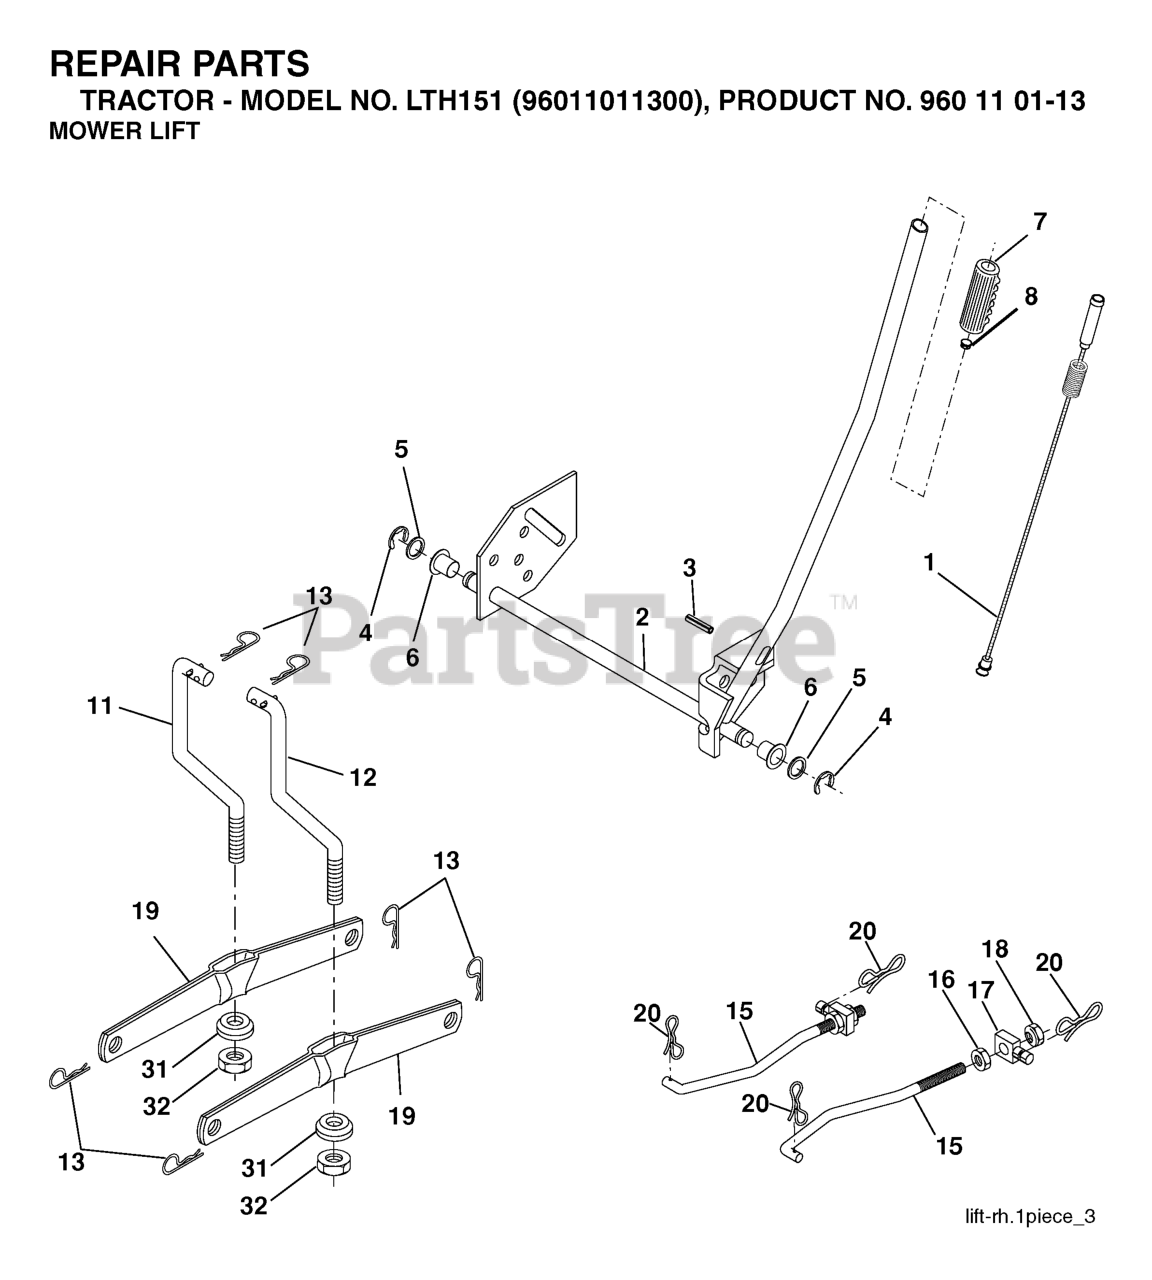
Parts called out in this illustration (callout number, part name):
1	WIRE ASM INNER W/ PLUNGER LT
2	SHAFT ASM R HANDLE
3	PIN GROOVE.
4	RETAINING RING LT
6	BEARING.NYLON
8	PLUNGER BUT KIT
11	LINK LIFT LH
12	LINK LIFT RH
13	RETAINER-SPRNG RB
15	LINK.SUSPENSION.FRONT
16	NUT.HEX.JAM.1/2-13
18	NUT.LK.W/WSH.1/2.
19	ARM.REAR.SUSPENSION
20	PIN.COTTER.7/16.BOW TI.
31	BEARING.PIVOT.LIFT
32	NUT CROWNLOCK 3/8-24
